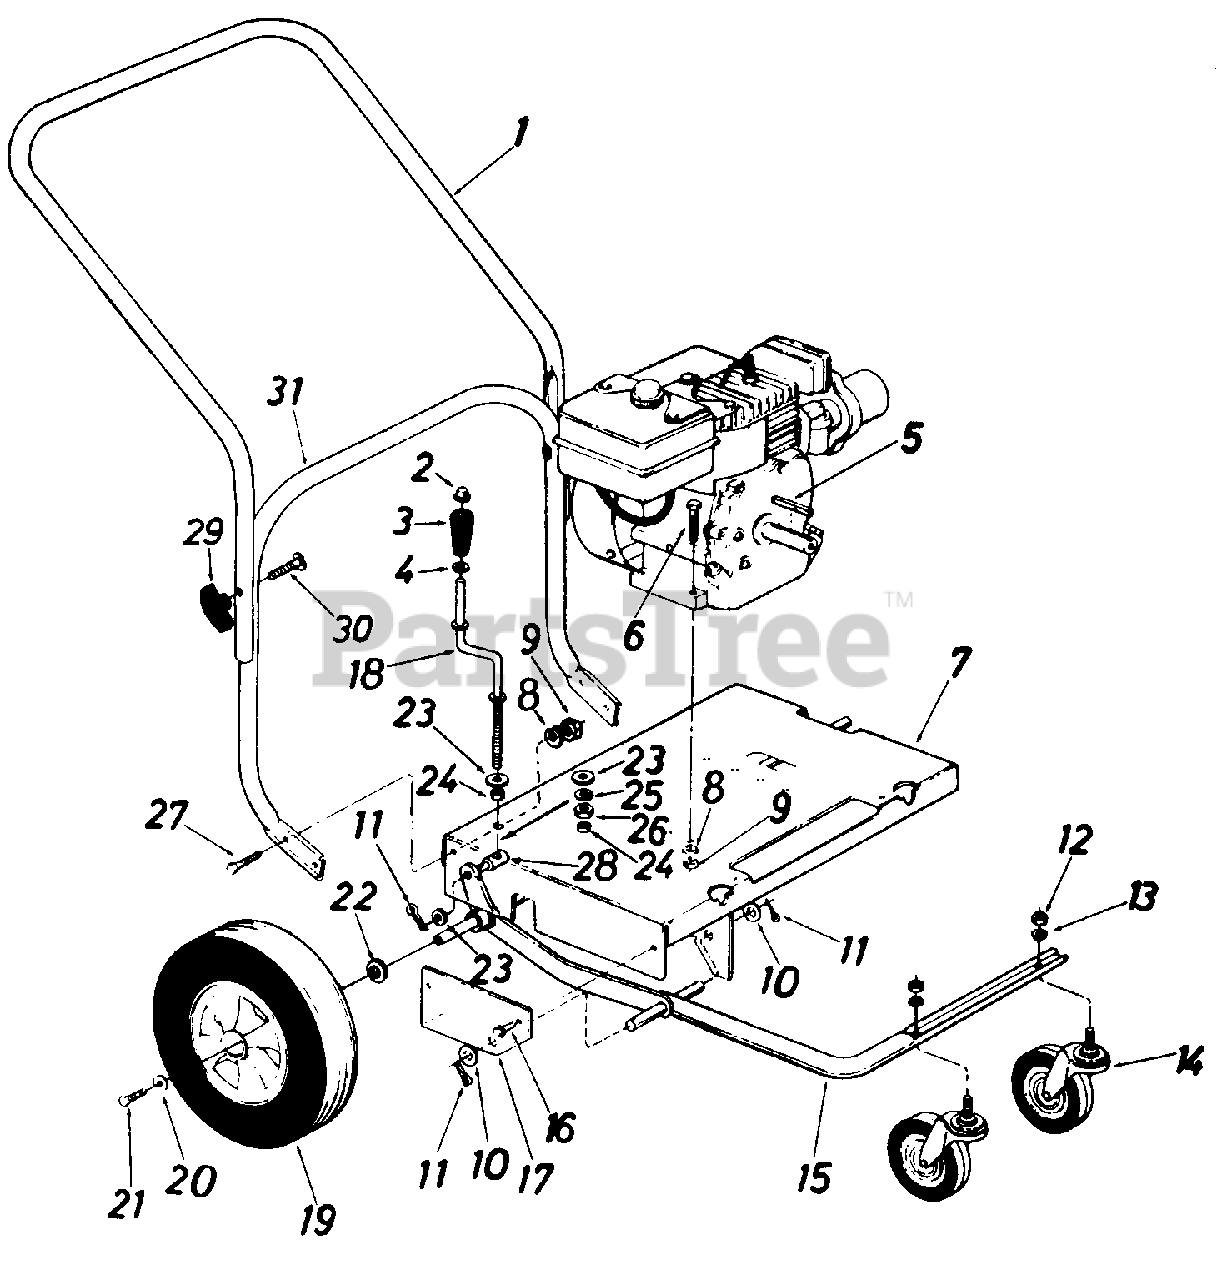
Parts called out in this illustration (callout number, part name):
2	Push Nut 3/8" Rod
3	Crank Knob
4	Fl.-Wash. .385" I.D. x .62" O.D.
5	Sq. Key 1/4" x 2.0" Lg.*
6	Hex Bolt 5/16-18 x 1.50" 4.*
9	Hex Nut 5/16-18 Thd.*
10	Fl.-Wash. .63" I.D. x 1.25" O.D.
11	Cotter Pin 1/8" Dia. x 1.0" Lg.
12	Hex Nut 1/2-13 Thd.*
13	L.-Wash. 1/2" I.D.*
14	Swivel Caster Wheel 5" Dia. x 1.25"
19	Wheel Ass'y. Comp. 12" x 3" (Plastic)(Incl. Bearings)
20	Fl.-Wash. 34" I.D. x .87" O.D.
21	Hex Locking Bolt 5/16-24 x .64" Lg.
22	Fl.-Wash.
23	Fl.-Wash. .38" I.D. x .57" O.D.
24	Spacer .382" I.D. x .50" x .180" Lg.
25	L.-Wash. 3/8" I.D.*
26	Hex Nut 3/8-8 Thd.
27	Hex Bolt 5/16-18 x .75" Lg.*
28	Ferrule
29	Hand Knob
30	Carriage Bolt 5/16-18 x 2.0" Lg.
